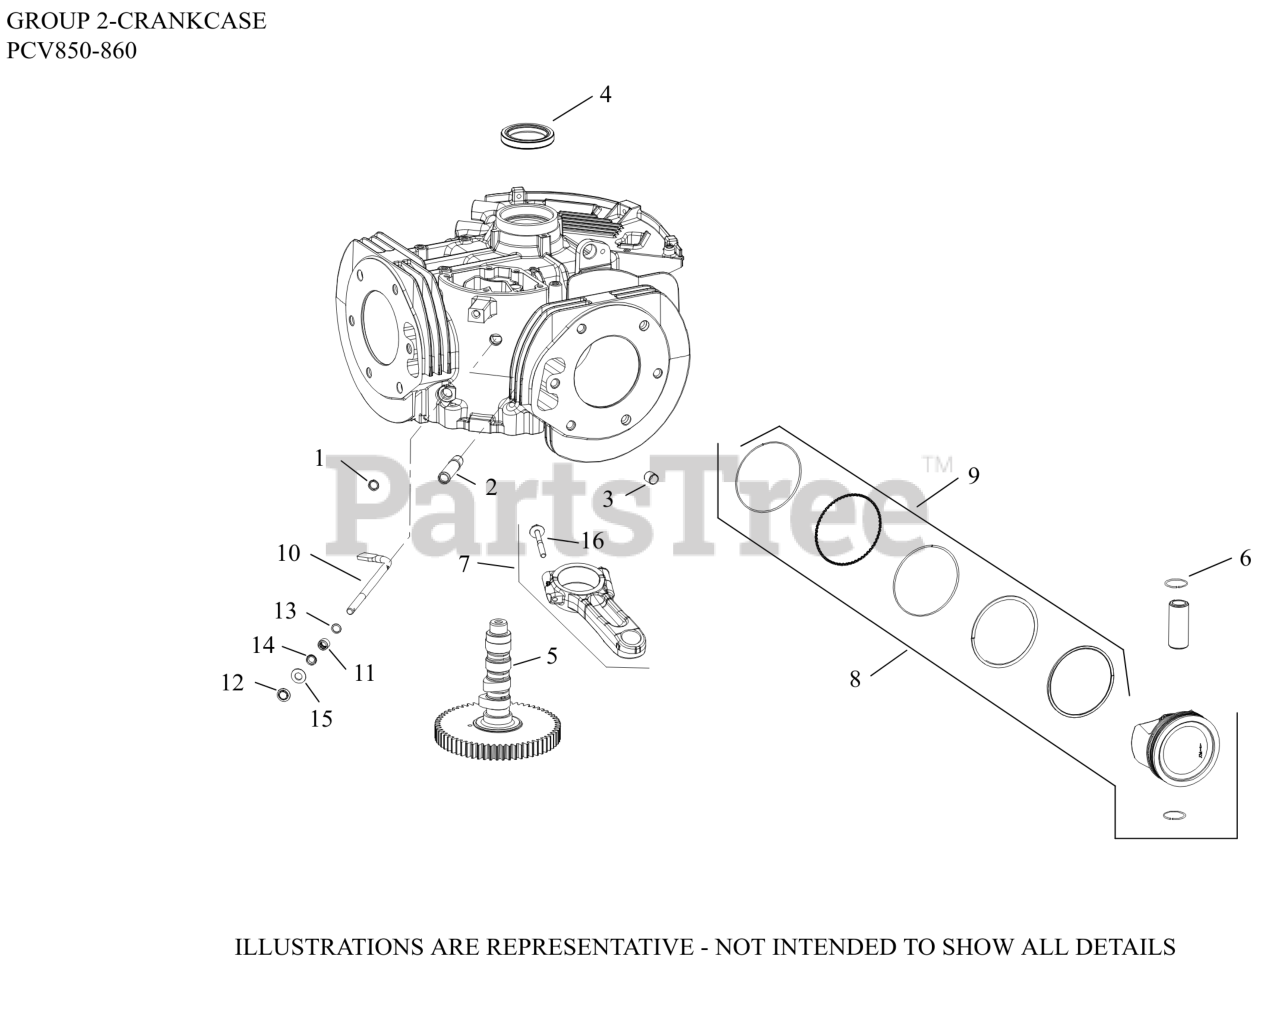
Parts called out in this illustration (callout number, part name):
2	FITTING, BREATHER HOSE
3	PIN, LOCATING
4	SEAL, OIL
4	SEAL, OIL-(#2503218S)
5	KIT, CAMSHAFT
6	RETAINER, PISTON PIN
7	ROD, CONNECTING ASSEMBLY
10	SHAFT, GOVERNOR CROSS
11	BEARING, NEEDLE
12	RETAINER, RING
13	WASHER, FLAT 11/32"
15	WASHER, FLAT 9 MM
NI	KIT, RING SET (STD)
NI	KIT, PISTON RINGS, PIN & CLIPS (STD)
NI	KIT, PISTON RINGS, PIN & CLIPS (.25)
NI	KIT, PISTON RINGS, PIN & CLIPS (.50)
NI	KIT, ROD BOLTS
